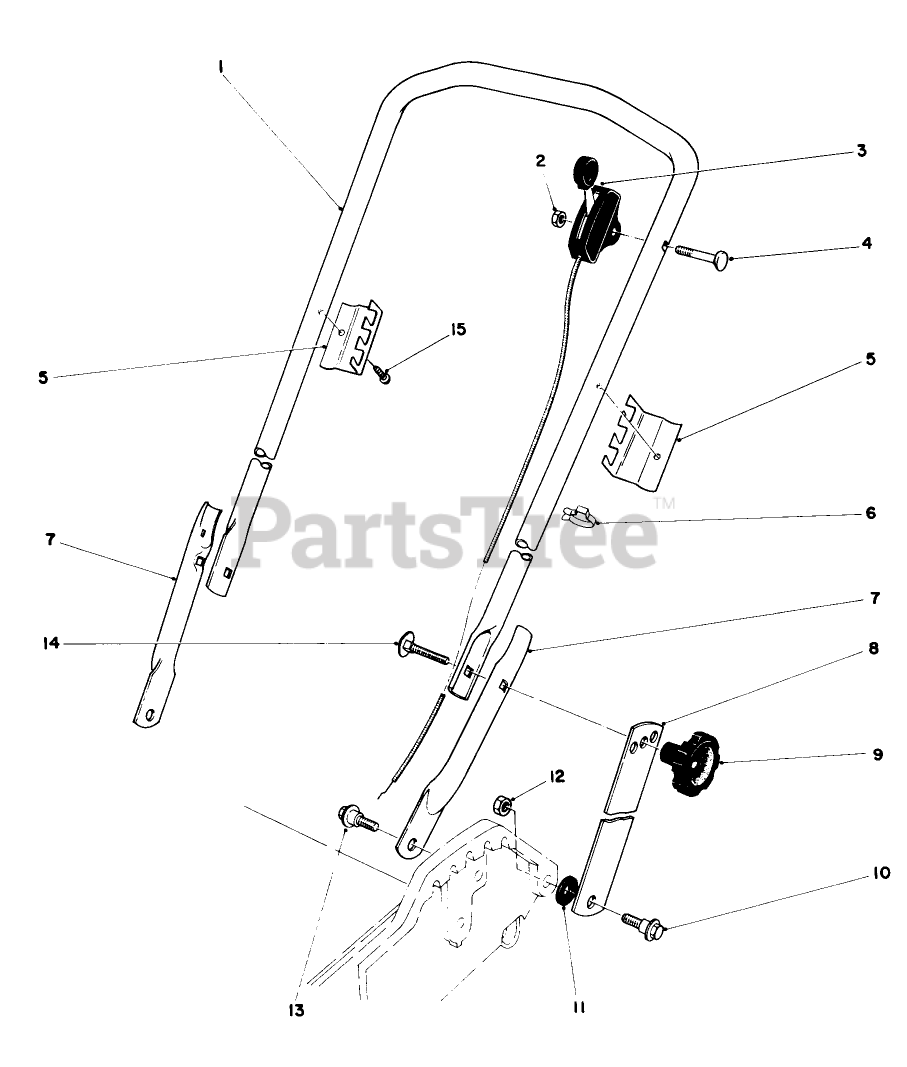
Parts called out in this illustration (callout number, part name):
2	NUT-LOCK, NI
3	SERVICE THROTTLE CONTRO
4	SCREW-HANDLE
6	BOWDEN CLIP
10	NUT-LOCK, NI
11	SCREW-SHOULDER
12	SPACER
13	SCREW-SHOULDER
15	SCREW-HWHTF
